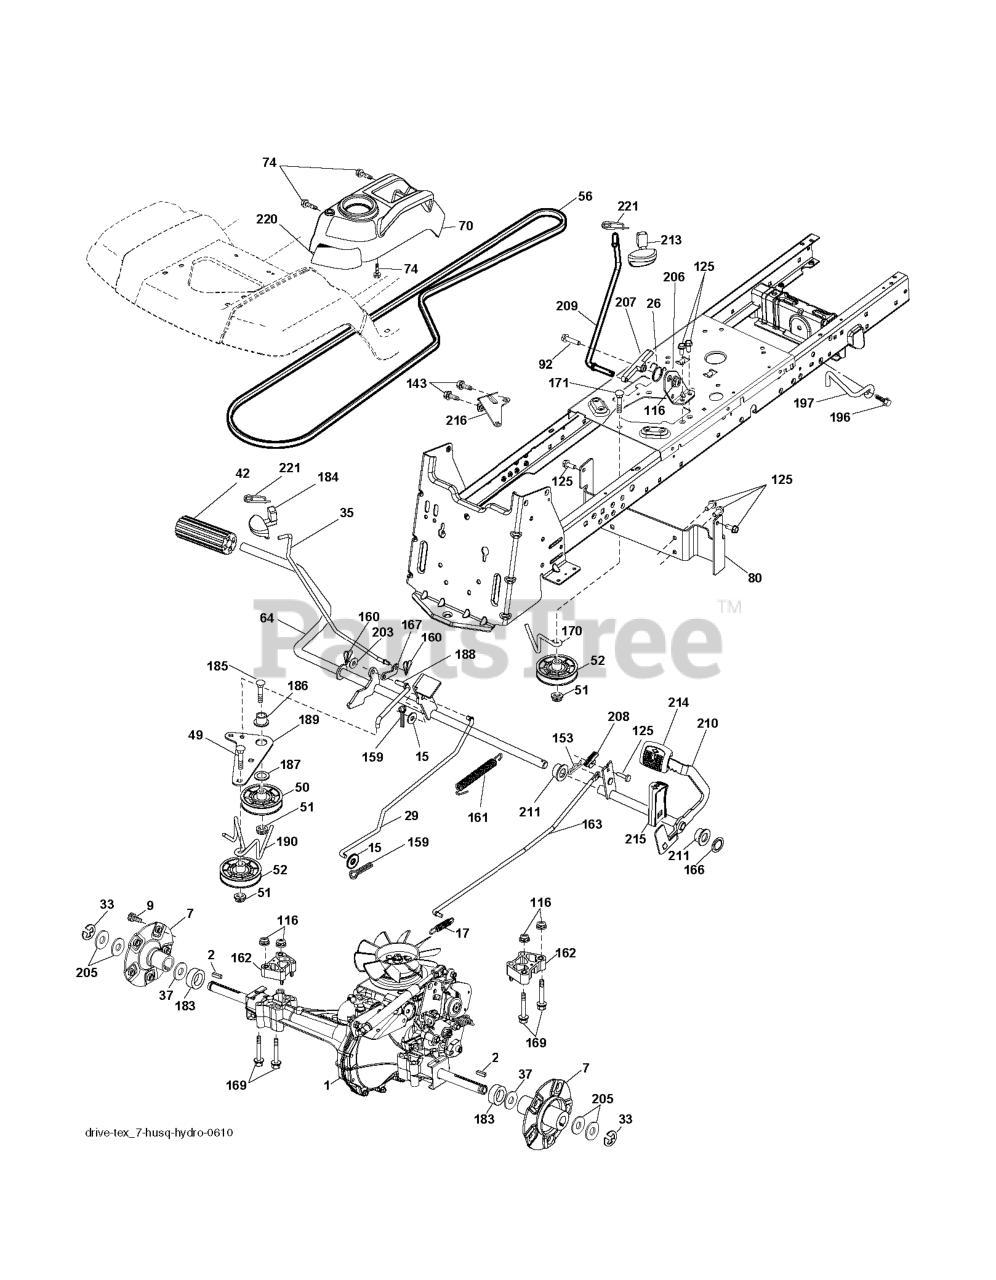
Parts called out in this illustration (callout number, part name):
2	KEY.SQUARE.187X2.500
7	HUB.ASM.WHEEL.REAR.22"
15	WASHER
17	SPRING.BRAKE.HG3000/3500
26	SPRING.RETURN.CRUISE
29	ROD.BRAKE.0610.PEDAL.CONTROL
35	ROD.BRAKE.PARKING.GT.H
42	PEDAL COVER T
50	IDLER.FLAT.910.OFFSET
51	NUT LOCK FLG 3/8-16 UNC
52	IDLER.V-GROOVE.910.OFFSET
64	SHAFT.ASM.PEDAL.BRK.CNTR
70	RP CONSOLE.ASM.PCH.W/TB
74	SCREW.HI-LO.CONSOLE
80	BRKT.STRP.TRQ.LT.HYD.C
92	BOLT
116	NUT LOCK HEX FLANGE 5/16-18
125	SCREW
143	Screw 5/16-18 x 1/2 Hex, Self Tapping 5/16-18 x 1/2
153	RETAINER M
159	COTTER PIN
160	RETAINER CLIP
161	SPRING.RETURN.CLUTCH.2006
162	SPACER.TRANSAXLE.18&22
163	ROD.PEDAL.CONTROL.0510
166	NUT.PUSH.625.2006
167	LATCH.BRAKE.SPRING
169	BOLT.HEX.FLNG.5/16-18X3.75
170	KEEPER.V-IDLER.CENTER.
183	SPACER.SPLIT.800X.350
184	HANDLE.PARKG.BRK.HUSQ X667
186	SPACER.RETAINER
187	WASHER 12/32X2X10GA
188	RP.LINK.CLUTCH.GROUND.DRIVE
189	BELLCRANK.GROUND.DRIVE.TEX.
190	KEEPER.BELLCRANK.DRIVE
196	SCREW 3/8-16X1
197	BRKT.ANIT-ROTATION.CLUTCH
203	WASHER
206	BRKT.MOUNT.LATCH.CRUIS
207	LATCH.CONTROL.CRUISE
208	GEAR.SECTOR.CONTROL.CR
209	ROD.CONTROL.CRUISE.GT.
210	ROCKER.ASM.PEDAL.CONTR
211	BEARING.NYLON
213	KNOB.CONTROL.CRUSIE.HU
214	PEDAL.FORWARD.TEX.GT.4
215	PEDAL.REVERSE.TEX.GT.4
216	BRACKET.PULLEY.IDLER.W/TEX
220	REFLECTOR.RH.TEX GT
221	RETAINER.SPRING.CLIP.H
222	WASHER
